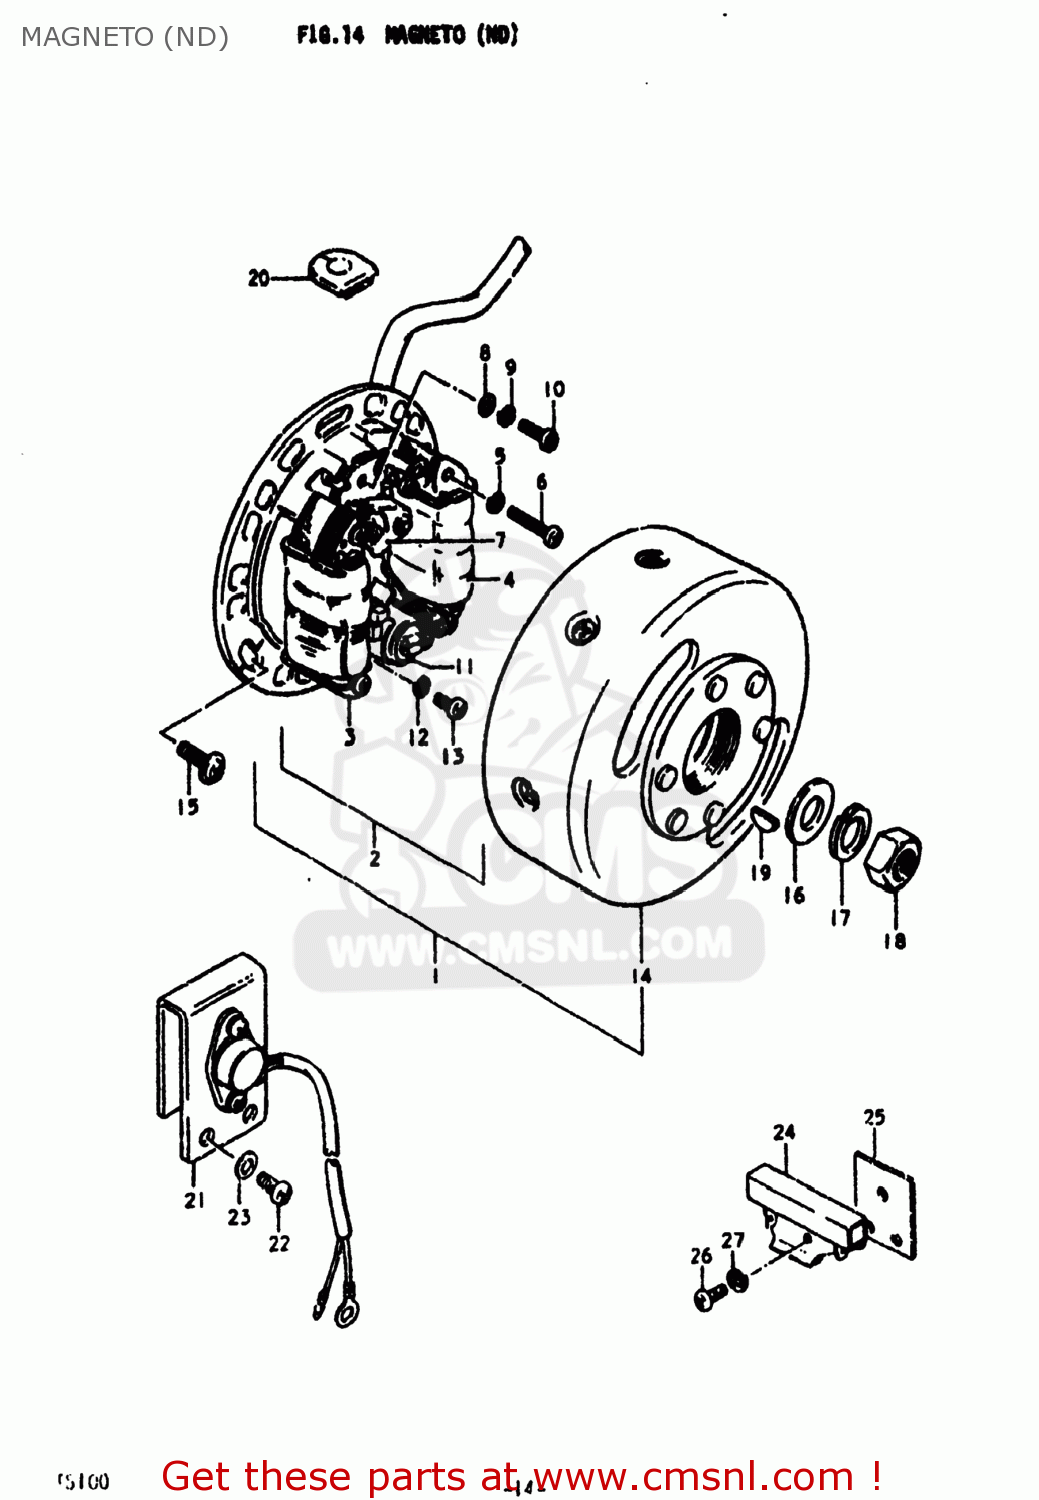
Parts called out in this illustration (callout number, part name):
1	MAGNETO ASSEMBLY
2	STATOR ASSEMBLY
3	COIL,LIGHTING
4	COIL
5	LOCK WASHER
6	SCREW 4X25
7	POINT ASSY,CONTACT
8	WASHER
9	LOCK WASHER
10	SCREW(4X10)
11	CONDENSER
12	LOCK WASHER
13	SCREW 4X10
14	ROTOR ASSEMBLY
15	SCREW(5X14)
16	WASHER
17	LOCK WASHER
18	NUT (10MM)
19	KEY
20	GROMMET
21	REGULATOR ASSEMBLY
22	SCREW 6X12
23	WASHER
24	RESISTOR ASSY,MAGNETO
26	SCREW
